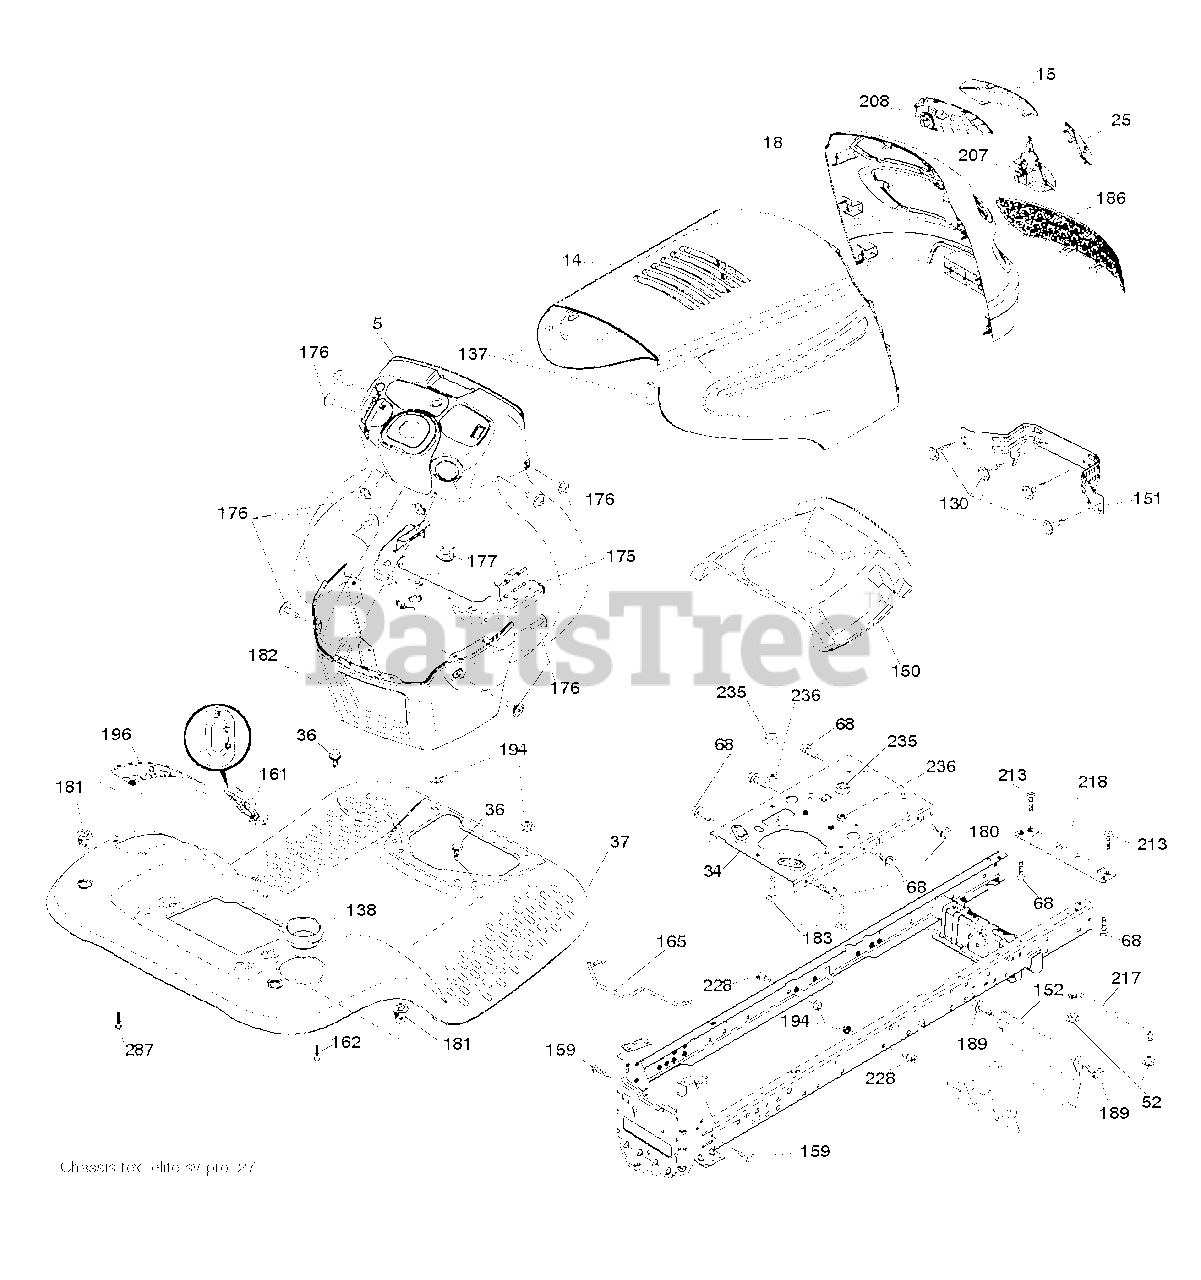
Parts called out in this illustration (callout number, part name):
34	PLATE.ENGINE.WELDED.CHASSIS
36	SCREW 5/16"
52	LOCKNUT
130	SCREW.#10 X 0.750.BOS THREAD
137	BUMPER.HOOD.LARGE.1.75"
138	CUPHOLDER.TL.TEX.BLACK
151	BRACKET PIVOT
152	SHIELD BROWNING
159	SCREW, 3/8-16X3/4
161	WINDOW.FUEL.LT.TEX.BLACK
162	SCREW.HI-LO.CONSOLE
165	SUPPORT.TANK.REAR.W/TE
175	CROSSMEMBER.LT
176	SCREW.#10-24X5/8.RN.QU
177	BUSHING STEERING
180	CHASSIS
181	FEND/FTRST.PCH.CPH.NFW
182	DASH.LOWER.LT.CCS
183	BOLT.5/16-18X1-1/4 FULL THD
189	SCREW
194	NUT LOCK HEX FLANGE 5/16-18
196	CONSOLE.ASM.DECKLFT.BL/RBT.TLT
207	BEZEL GRILL RH
208	BEZEL GRILL LH
213	BOLT
217	ROD.PIVOT.HOOD
218	X-PIECE.HOOD.STOP.NON/
228	STUD.FASTNER.W/ANTI-ROTATE
235	SPACER FENDER
236	NUT.CENTERLOCK.5/16-
